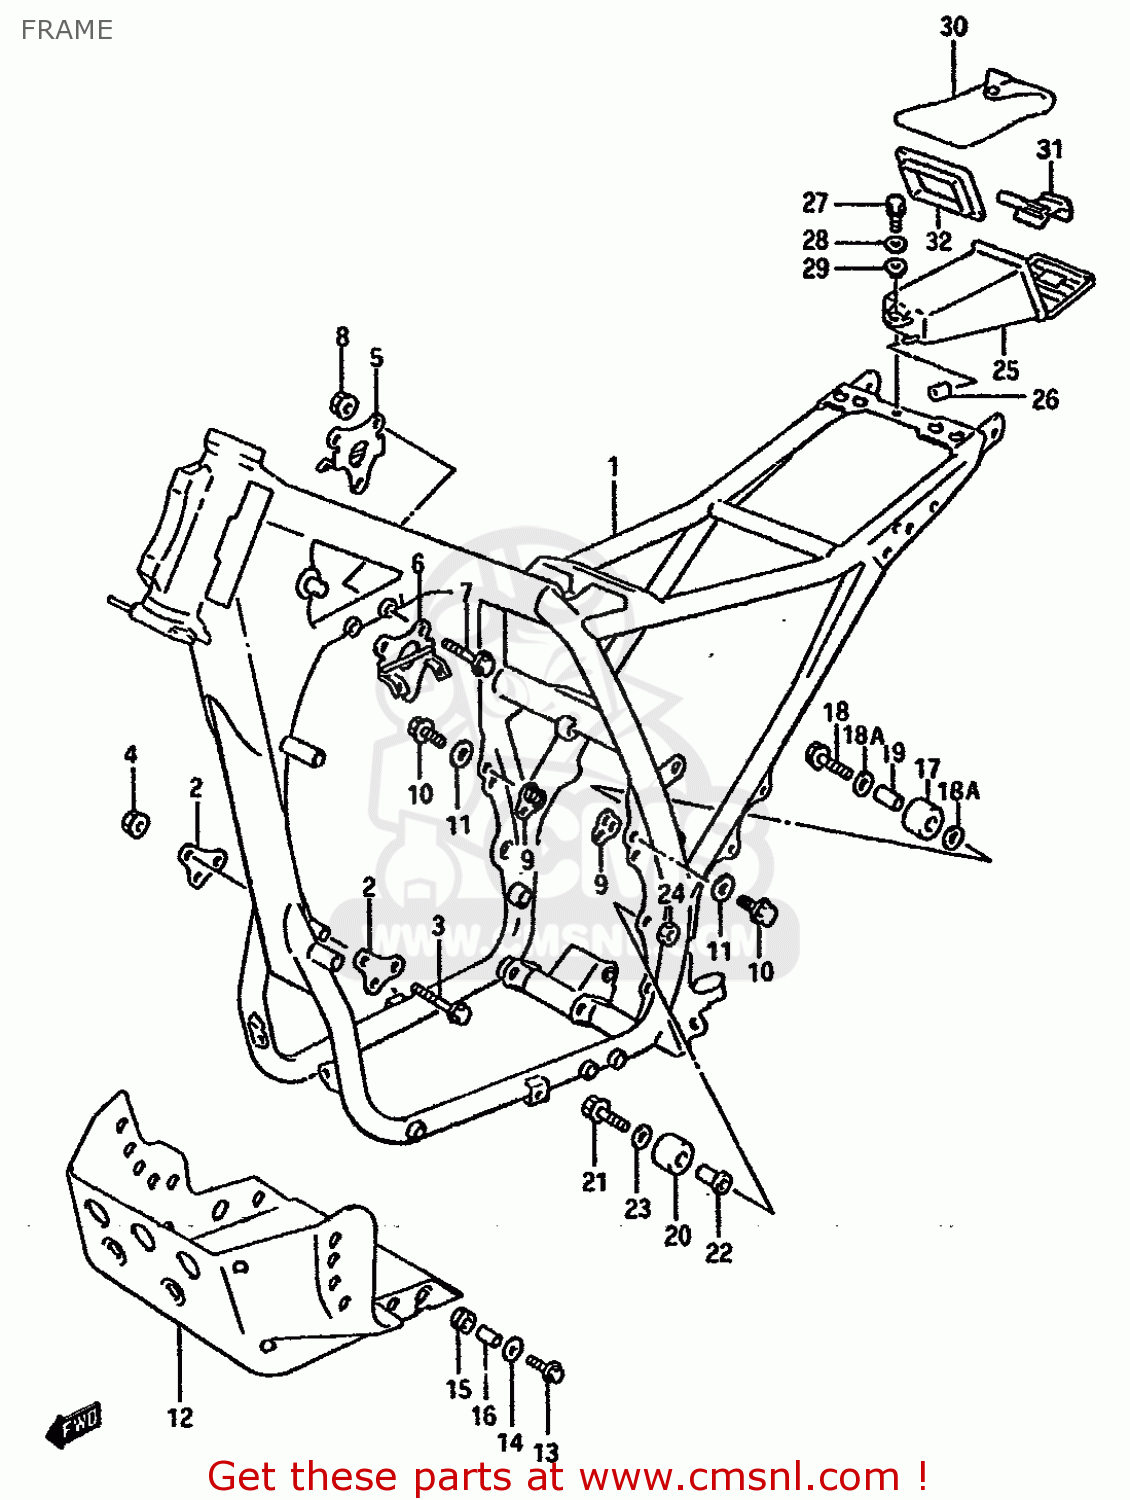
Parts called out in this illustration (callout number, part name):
1	FRAME (BLUE)
2	PLATE,FRONT (BLUE)
3	BOLT 8X70
4	NUT
5	PLATE,UPPER RH (BLUE)
6	PLATE,UPPER LH (BLUE)
7	BOLT
8	NUT
9	PLATE,REAR (BLUE)
10	BOLT
11	LOCK WASHER
12	PROTECTOR,ENGINE
13	BOLT
14	WASHER
15	CUSHION
16	SPACER (6.1X9X9)
17	ROLLER,CHAIN CONTROL
18	BOLT(8X41)
18A	WASHER
19	SPACER (8.6X13.8X28)
20	ROLLER,CHAIN CONTROL
21	BOLT(10X52)
22	SPACER,CHAIN ROLLER, LWR
23	WASHER
24	NUT 10MM
25	HOLDER TOOL
26	CUSHION
27	BOLT
28	WASHER,LOCK
29	WASHER
30	TOOL ASSY
31	BAND
32	CUSHION,TOOL HOLDER
